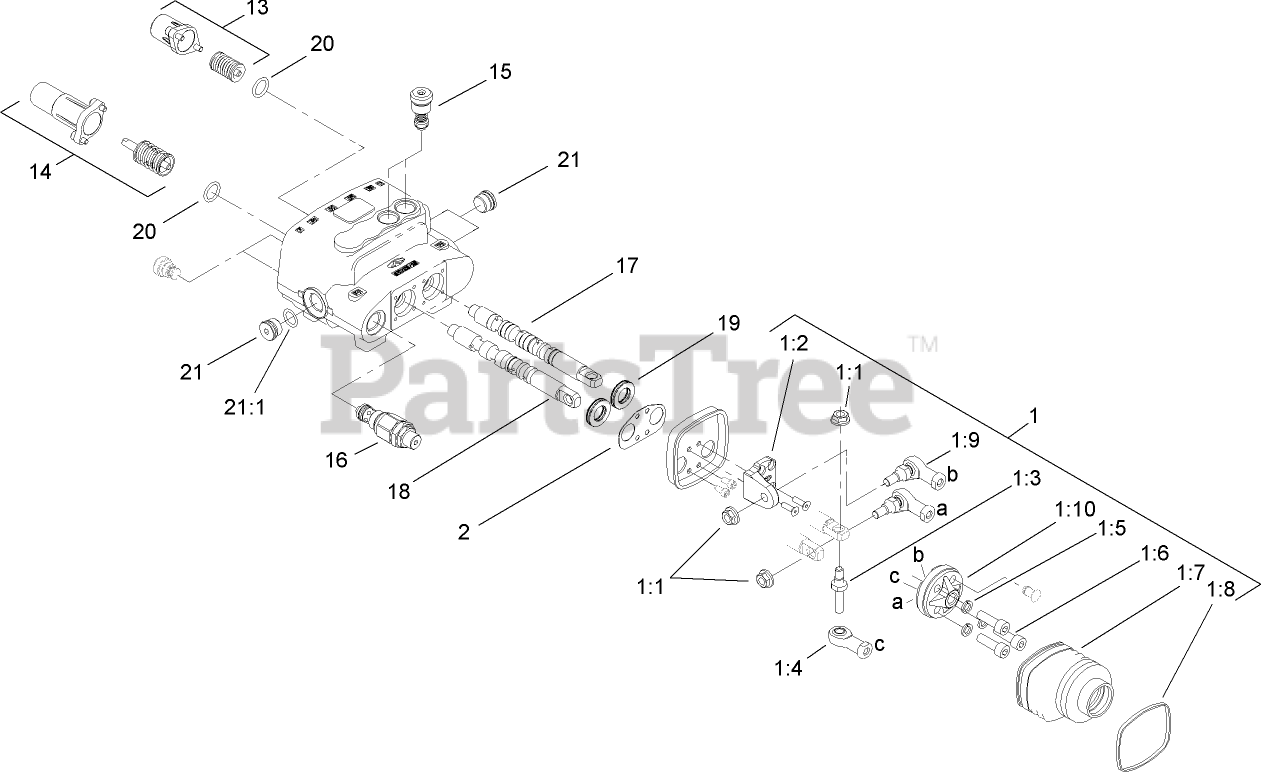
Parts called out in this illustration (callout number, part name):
1	JOYSTICK KIT
1:2	PIVOT-JOYSTICK
1:3	PIN-JOYSTICK
1:4	END-ROD
1:5	WASHER-LOCK, SPRING
1:6	SCREW-HSH
1:7	BELLOW-RUBBER
1:8	TIE-CABLE
1:9	JOINT-JOYSTICK
1:10	HOLDER-ARTICULATED
2	SEAL-JOYSTICK
13	VALVE SPRING KIT
14	DETENT SPRING KIT
15	VALVE-RELIEF
16	VALVE-RELIEF, MAIN
17	SPOOL-VALVE
18	SPOOL-VALVE
19	SEAL-VALVE, SPOOL
20	SEAL-VALVE
21	PLUG-HEX
21:1	O-RING
